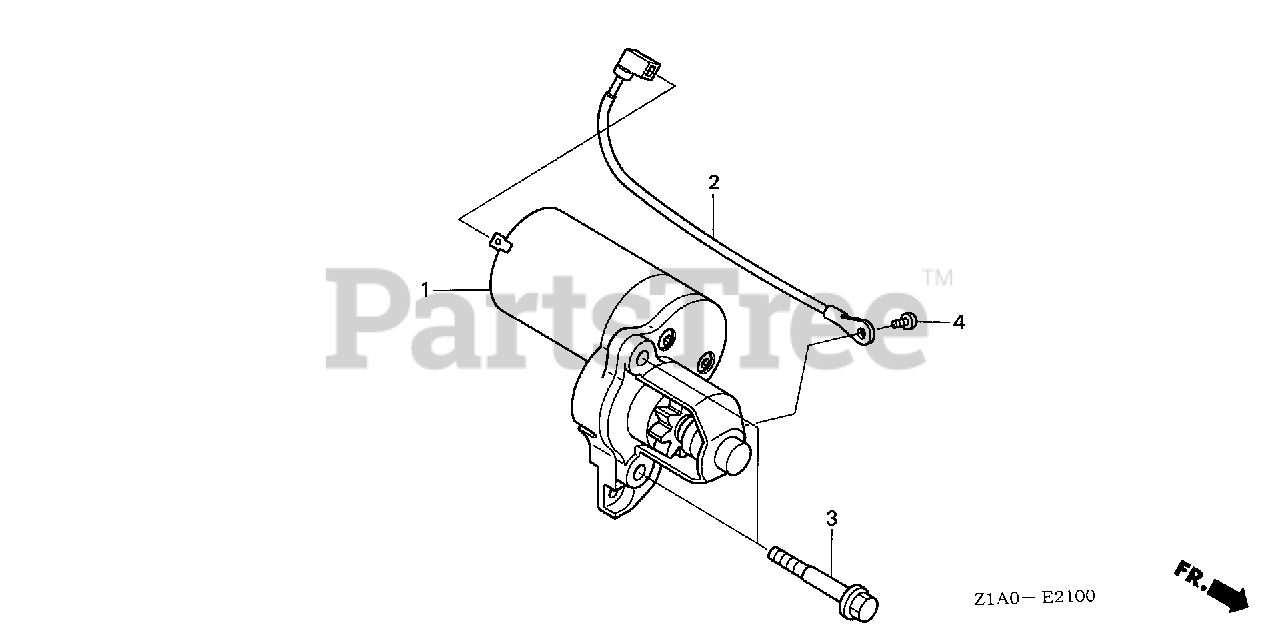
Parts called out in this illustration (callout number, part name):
1	STARTER MOTOR ASSY.
2	WIRE, TERMINAL GROUND
3	BOLT, SPECIAL (6MM)
4	SCREW, PAN (5X8)
